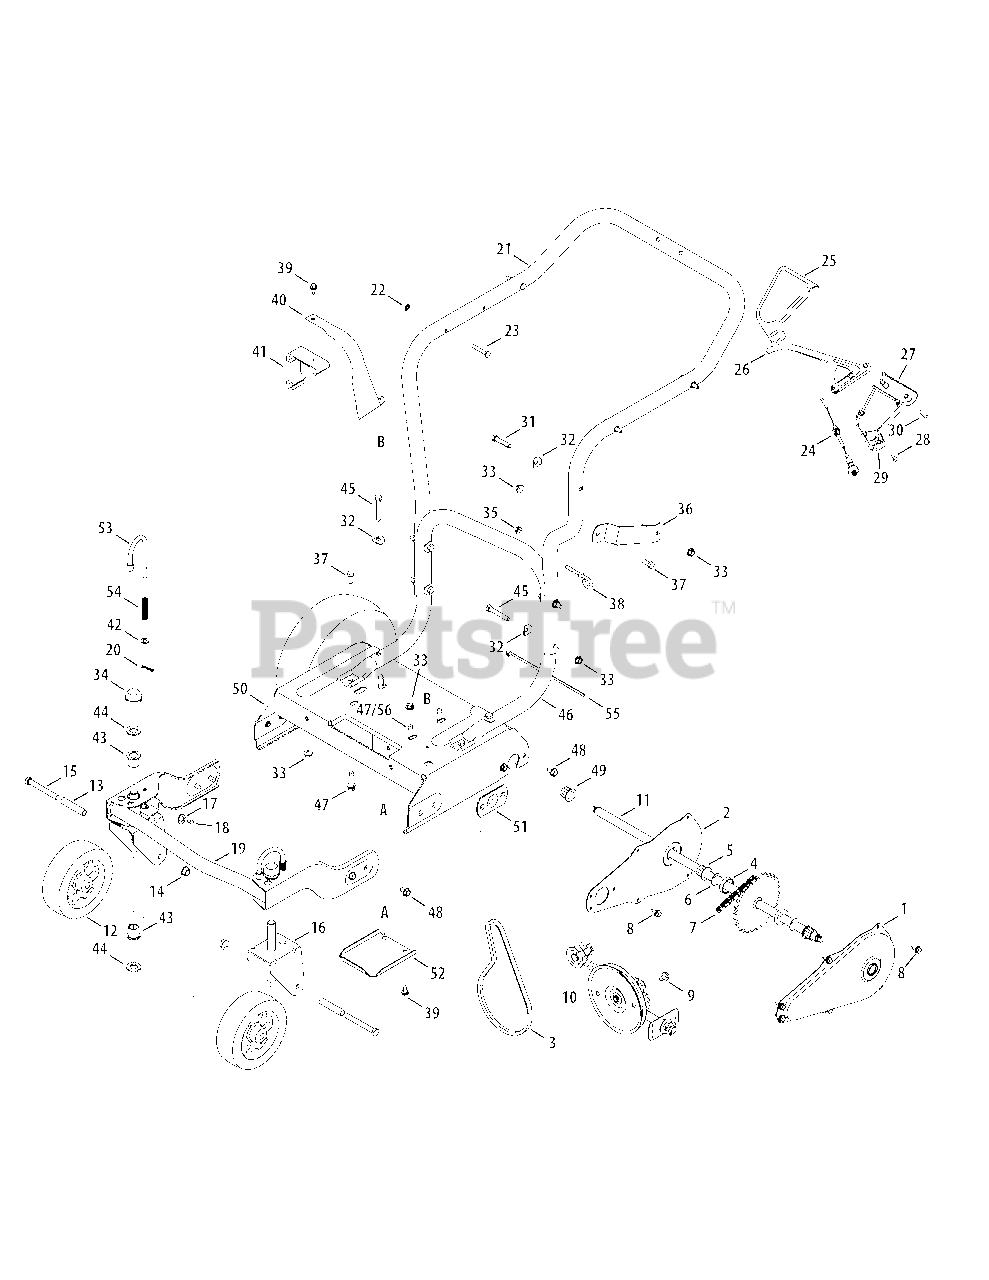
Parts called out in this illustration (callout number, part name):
1	Chain Case - LH
2	Chain Case - RH
5	Hex Flange Bearing
6	Flat Washer
8	TT Screw, 1/4-14 x 0.625"
9	Hex Washer Screw, 5/16
10	Chipper Shredder Trans. Ass’y.
11	Axle Assembly
12	Wheel, 6.0 x 2.0
14	Flange Lock Nut, 3/8-16
15	Hex Cap Screw, 3/8-16 x 3.0
16	Bracket Assembly
17	Flat Washer, .203 ID x.403 OD
18	Grease Fitting, 3/16
19	Bracket Assembly
20	Cotter Pin
23	Stud Pin, .250 x 1.75
24	Clutch Cable - 56"
25	Upper Clutch Cover
26	Drive Lever
27	Lower Clutch Cover
28	Screw, #10-12 x.750
29	Mounting Cable Cap
30	Screw, #10-16 x 1.25
31	Hex Cap Screw, 5/16-18 x 1.50
32	Shldr. Washer, .320 ID x.93 OD
33	Hex Flange Lock Nut, 5/16-18
35	Hex Nut, 1/4-28
36	Discharge Chute Bracket
37	Hex Cap Screw, 5/16-18 x.75
39	Hex Washer Screw, 1/4-14 x.625
40	Belt Cover
41	Engine Mounting Adapter
42	Flat Washer, .330 ID x.630 OD
43	Flange Bearing, .632 ID
44	Flat Washer, 5/8 ID x 1.0 OD
45	Hex Cap Screw, 5/16-18 x 1.75
46	Lower Push Handle
47	Screw, 3/8-16 x 1.25
48	Hex Wash. Screw, 5/16-18 x.625
49	Hex Flange Bearing, .631 x.720
50	Frame Assembly
52	Transmission Cover
54	Compression Spring
55	Cable Tie
56	Hex Cap Screw, 5/16-18 x 1.25
